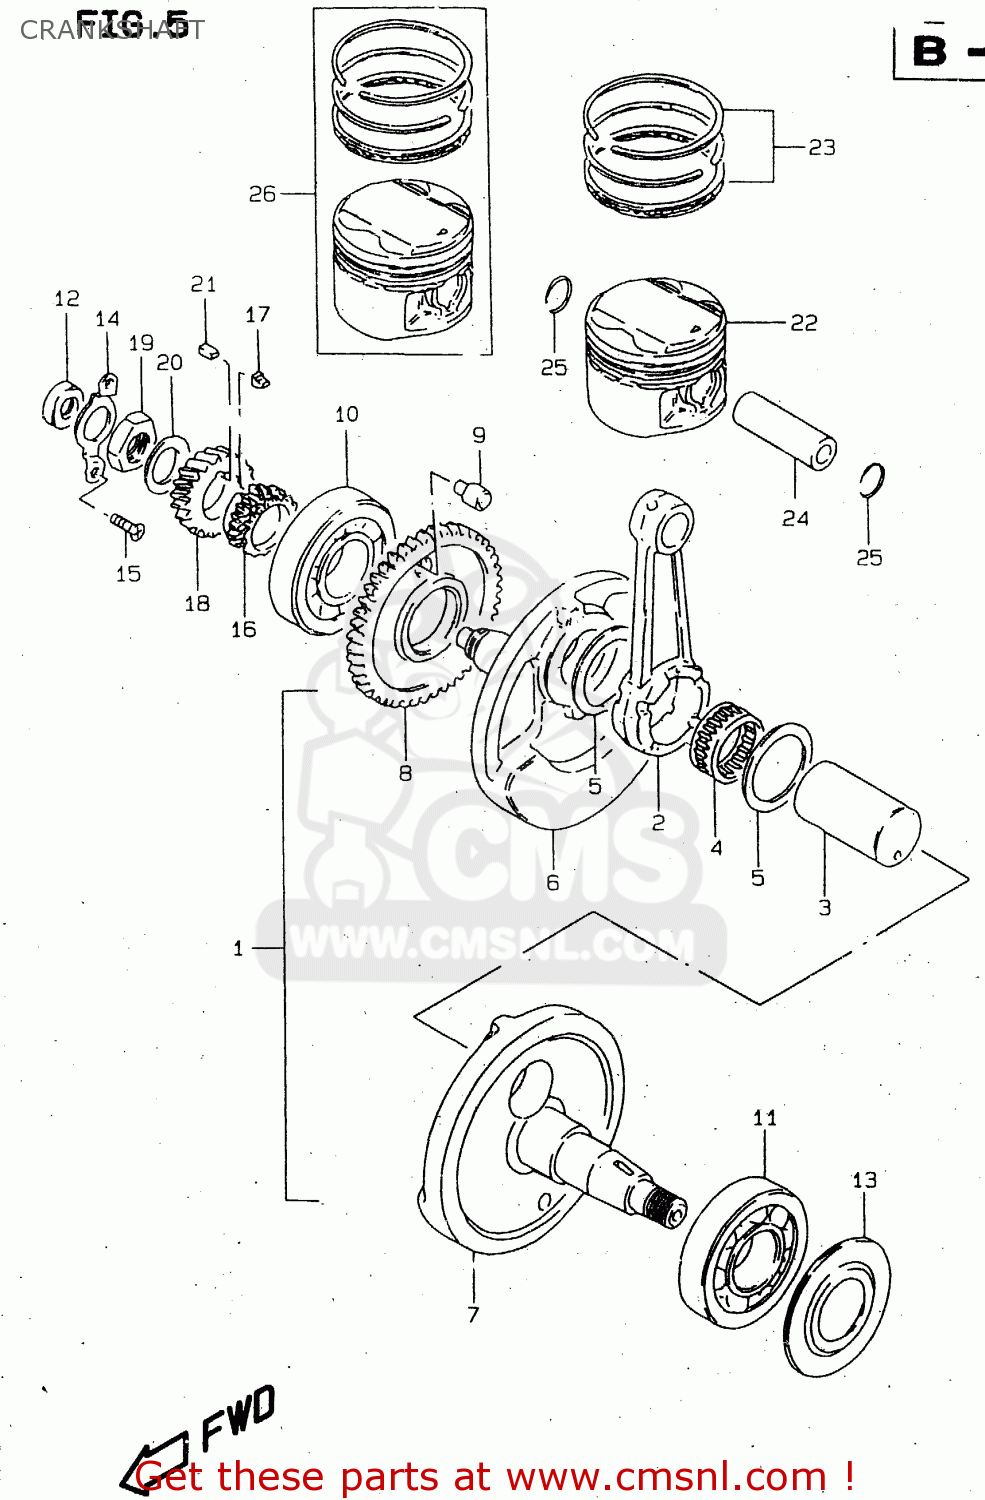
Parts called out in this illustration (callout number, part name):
1	CRANKSHAFT ASSEMBLY
2	ROD,CONNECTING
3	PIN,CRANK
4	BEARING(31X39X21)
5	WASHER(31X48.5X1)
6	CRANKSHAFT,R
7	CRANKSHAFT,LEFT
8	GEAR,CRANK BALANCER DRIVE
9	PIN
10	BEARING(30X72X19)
11	BEARING(35X80X21)
12	SEAL,OIL(14X26X6)
13	WASHER,CRANKSHAFT OIL SEALING
14	RETAINER,CRANKSHAFT BEARING,R
15	SCREW
16	SPROCKET,CAM CHAIN DRIVE(NT:21
17	KEY,SPROCKET
18	GEAR,PRIMARY DRIVE NO.21
19	NUT (20MM)
20	WASHER
21	KEY
22	PISTON (72.00MM)
23	RING SET,PISTON
24	PIN,PISTON
25	CIRCLIP,PISTON PIN
26	PISTON SET(OS:0.5)
